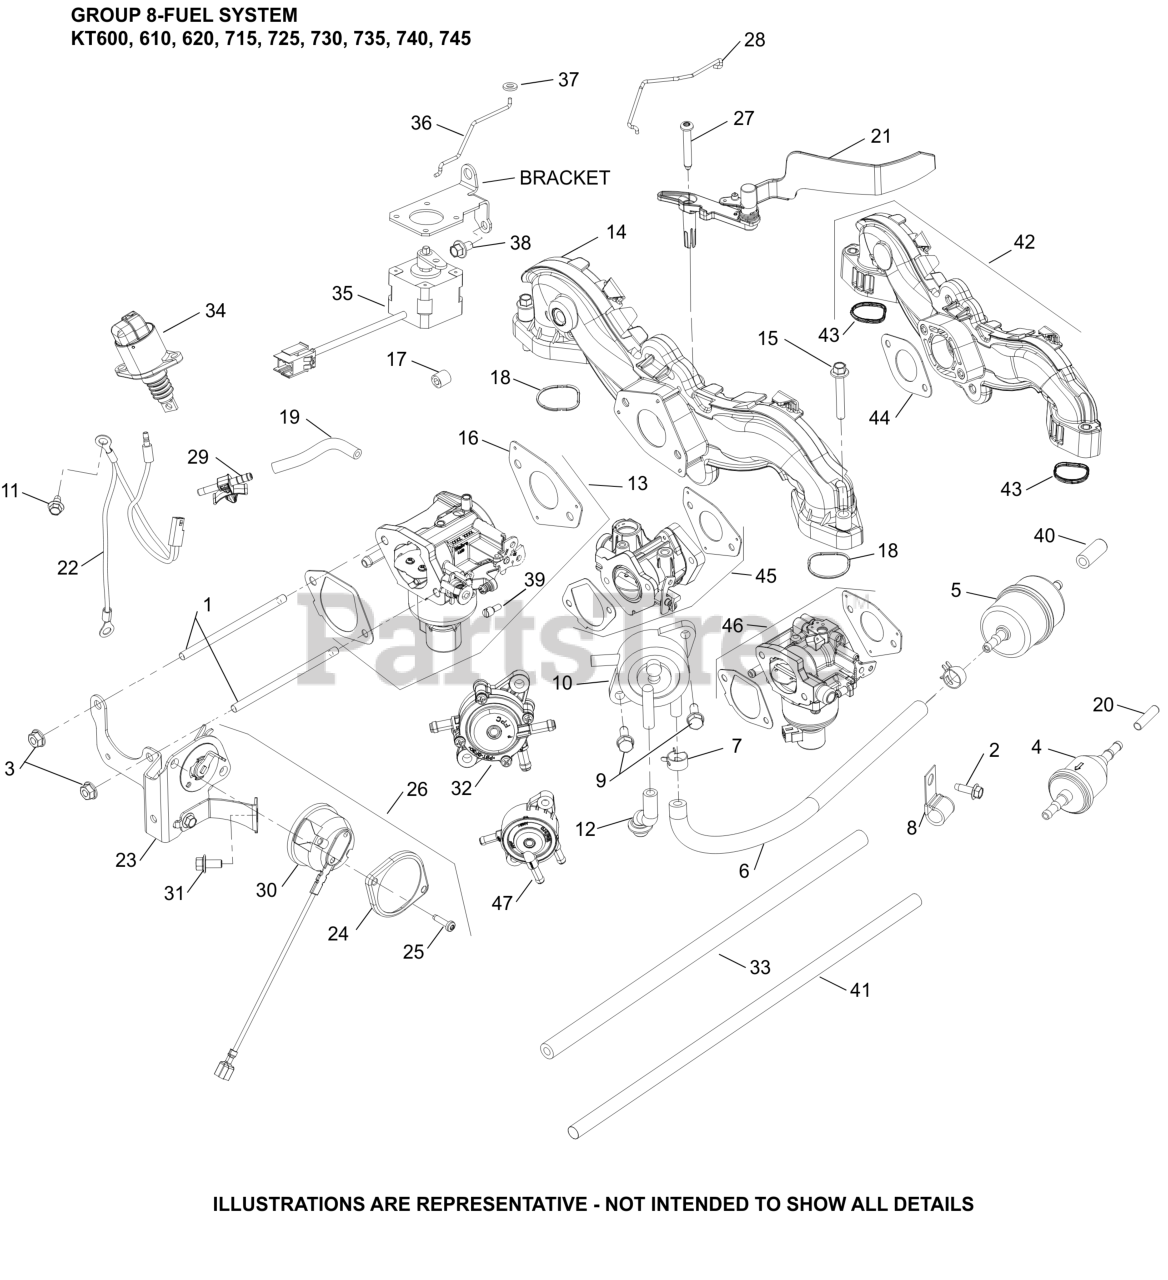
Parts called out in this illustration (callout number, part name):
3	NUT, FLG M6X1.0
4	FILTER,FUEL 51 MICRON (FUEL PUMP)
6	HOSE,LW PERM.FUEL 24.00"-USE 25 111 81-S
7	SPRING CLAMP, HOSE
8	CLIP, CABLE (KM)
9	SCREW, TAP M6X1.7X18
11	SCREW, THREAD FORMING
13	KIT, CARB (WALBRO)
15	SCREW, FLG M6X1.0X40
16	GASKET, CARBURETOR-(#2404191S)
42	INTAKE MANIFOLD W/GASKETS
43	O-RING, INTAKE PORT
44	GASKET, CARBURETOR (PIM, CV)
47	PUMP, FUEL (PULSE)
NI	KIT, HIGH ALT (WALBRO) (4000-8000 FT)
NI	KIT,REPAIR OVERHAUL(WALBRO)
NI	KIT,BOWL O-RING(WALBRO)
NI	KIT,SOLENOID REPAIR(WALBRO)
NI	KIT,REPAIR FLOAT(WALBRO)
